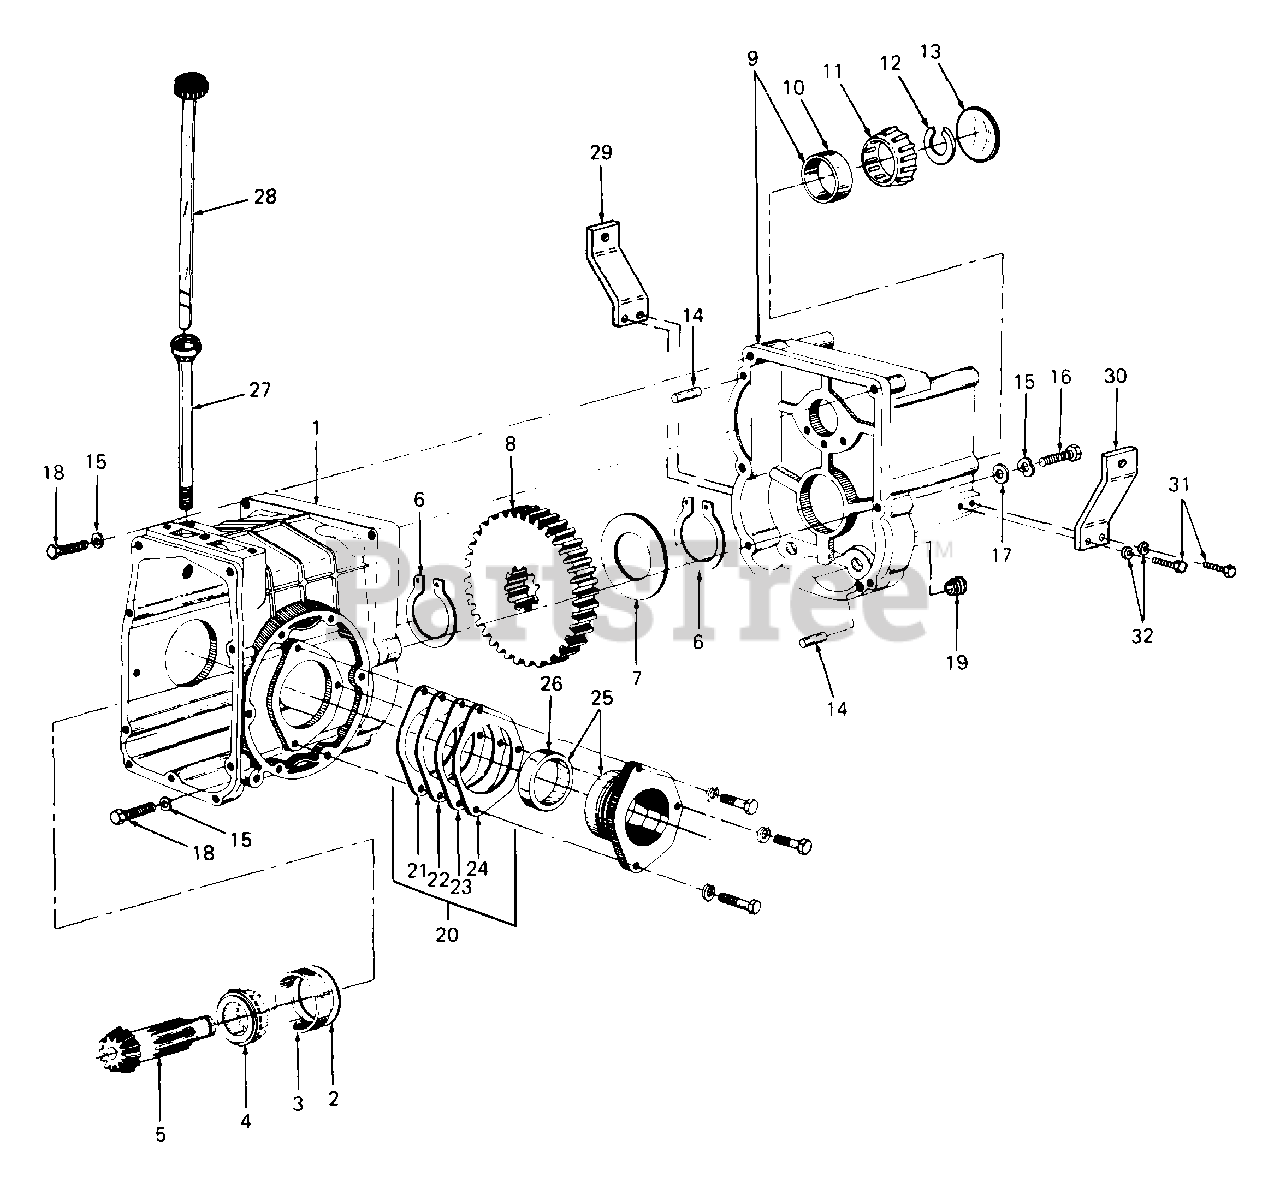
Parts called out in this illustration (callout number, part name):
1	Housing Assy, Rear Transaxle
2	Shim, Rear Bearing Cup, .004 Thk
3	Cup, Roller Bearing
4	Cone, Roller Bearing
5	Shaft, Bevel Pinion
6	Ring, Retaining, 1.312 Dia
7	Spacer, Gear
8	Gear, Reduction - 66T
9	Housing Assy, Adapter w/Cup
10	Cup, Roller Bearing
11	Cone, Roller Bearing
12	Retainer, Front Bearing, .125 Thk
13	Plug, Expansion, 2.12 OD
14	Pin, Dowel, 3/8 Dia x 5/8 Lg
15	Washer, Spring, .445 x .75 x .017 Thk
16	Screw, Hex Cap, 7/16-14 x 2.5 Lg GR5
17	Washer, Flat, .46 x .875 x .060 Thk
18	Screw, Hex Cap, 7/16-14 x 1.75 Lg GR5
19	Plug, Drain
20	Shim Package
21	Shim, Bearing Retainer, .004 Thk
22	Shim, Bearing Retainer, .007 Thk
23	Shim, Bearing Retainer, .014 Thk
24	Shim, Bearing Retainer, .028 Thk
25	Retainer Assy, Bearing w/Cup
26	Cup, Roller Bearing
27	Tube, Dipstick
28	Blade Assy, Dipstick
29	Bracket, Trans Mtg - LH
30	Bracket, Trans Mtg - RH
31	Bolt, Hex Patch, 3/8-16 x 1.0 Lg GR5
32	Washer, Lock, 3/8
